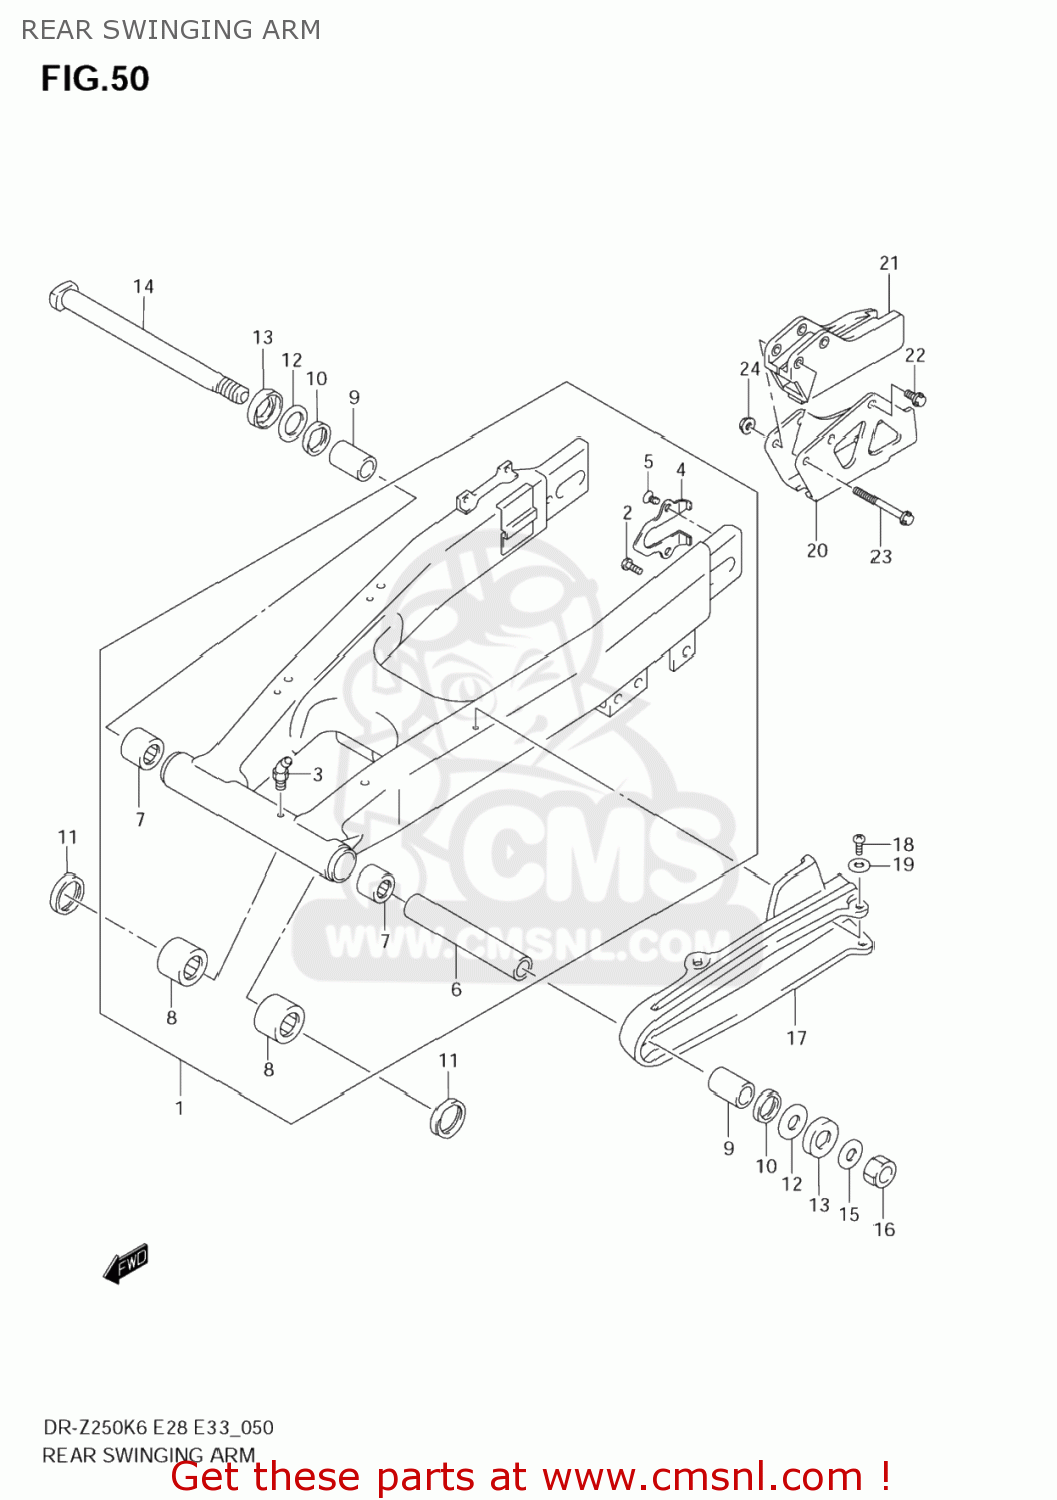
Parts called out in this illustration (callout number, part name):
1	SWINGINGARM ASSY,RR
2	STOPPER,CHAIN ADJUSTER
3	NIPPLE,GREASE
4	PLATE,RR SWING ARM AXLE
5	SCREW(5X8)
6	SPACER,SWGARM PIVOT CTR
7	BEARING(22X29X30)
8	BEARING(20X27X23.5)
9	SPACER,SWGARM PIVOT BRG
10	SEAL,OIL(22X29X4)
11	SEAL,OIL(20X27X5)
12	WASHER
13	COVER,SWINGINGARM PIVOT
14	SHAFT,SWINGING ARM PIVOT
15	WASHER
16	NUT
17	BUFFER,CHAIN TOUCH DEFENSE
18	SCREW
19	WASHER
20	PLATE,CHAIN GUIDE
21	GUIDE,CHAIN
22	BOLT
23	BOLT
24	NUT
